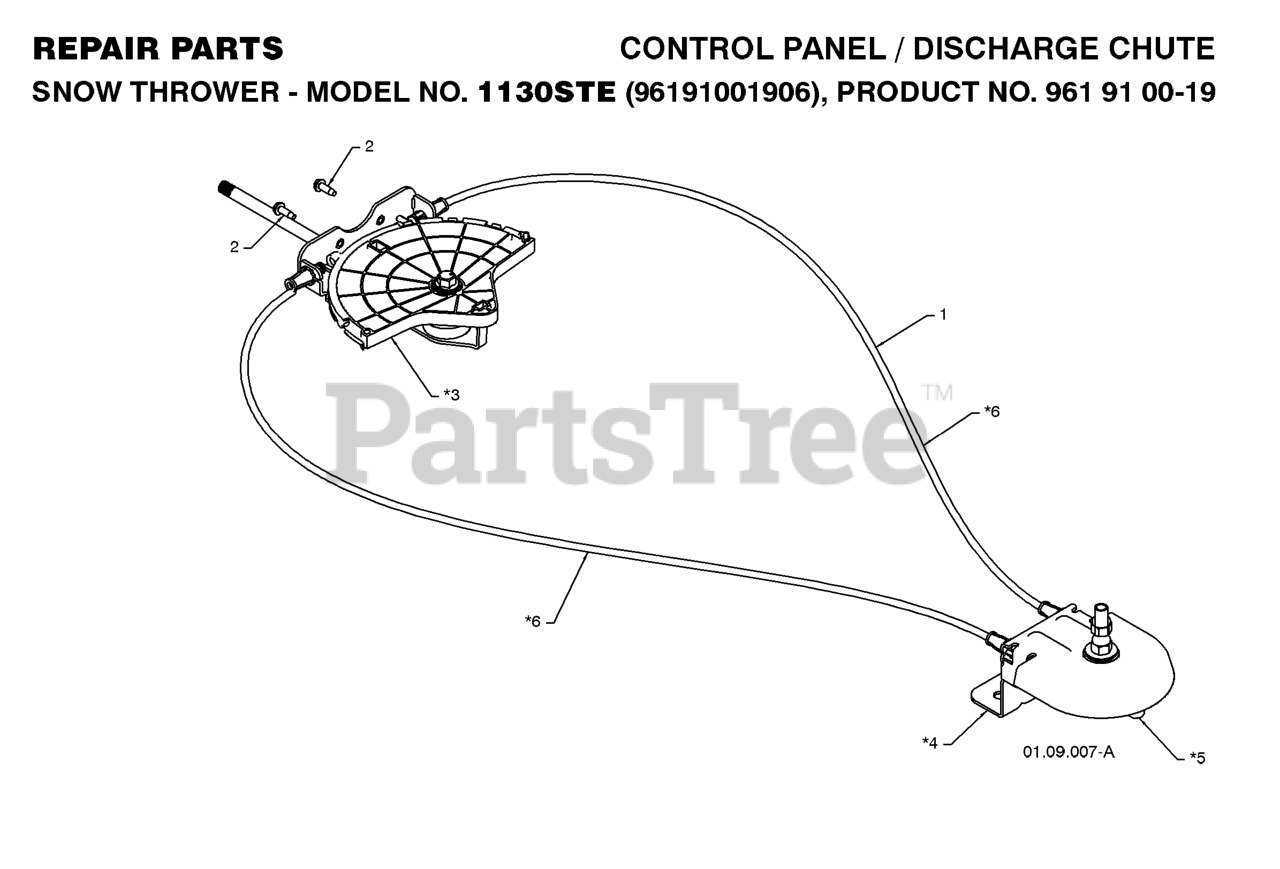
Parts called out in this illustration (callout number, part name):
1	DECAL.FENDER.WARNING.ENG
1	RP.LEVER/CABLE.ASM.ROTATOR
2	DECAL.DECK.AIR.INDUCTION.HUSQ
2	SCREW #10-24 X 5/8
3	DECAL.WARN.KEEP.HAND.AWAY
6	DECAL.ENG.BSM44.ED.27HP.278171
8	DECAL.MOWER.SCH.48/54
9	DECAL BTRY SYMBOLS
14	DECAL.SDPNL.2748GLS.ENDUR.HUSQ
15	DECAL HOOD CUST. RESP.
16	EMBLEM.HOOD.HUSQ.DEALER
17	DECAL.RPL.BSM44.ENDUR.TGW.48K6
